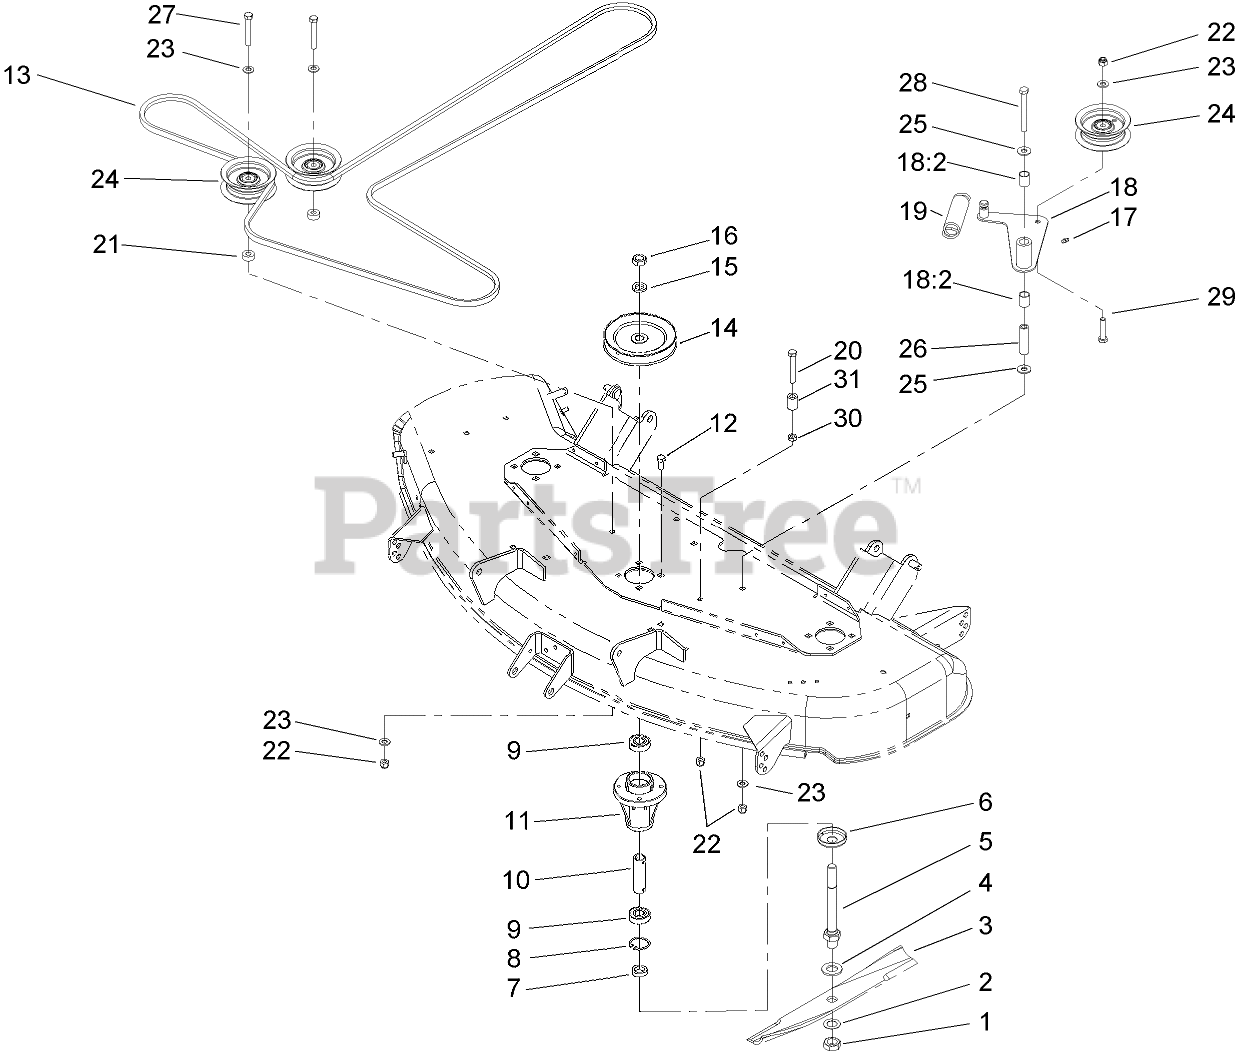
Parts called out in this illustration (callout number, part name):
1	NUT-JAM
2	WASHER-FLAT
3	BLADE KIT (3 PACK)
4	WASHER-FLAT
5	SHAFT-SPINDLE
6	CUP-SPINDLE
7	SPACER-BLADE
8	RING-RETAINING
9	BEARING-BALL
11	HOUSING-SPINDLE
12	SCREW-HH
13	BELT-V
14	PULLEY ASM
15	WASHER-LOCK
16	NUT-JAM
17	FITTING-GREASE
18	IDLER ARM ASM
18:2	SLEEVE-BEARING
19	SPRING-EXTENSION
20	SCREW-HH
21	SPACER
22	NUT-LOCK, NI
23	WASHER-FLAT
24	PULLEY-IDLER, FLAT
25	WASHER-HARDENED
26	BUSHING-PIVOT, IDLER
27	SCREW-HH
28	SCREW-HH
29	SCREW-HH
30	NUT-HEX
31	TUBE-INTERLOCK
